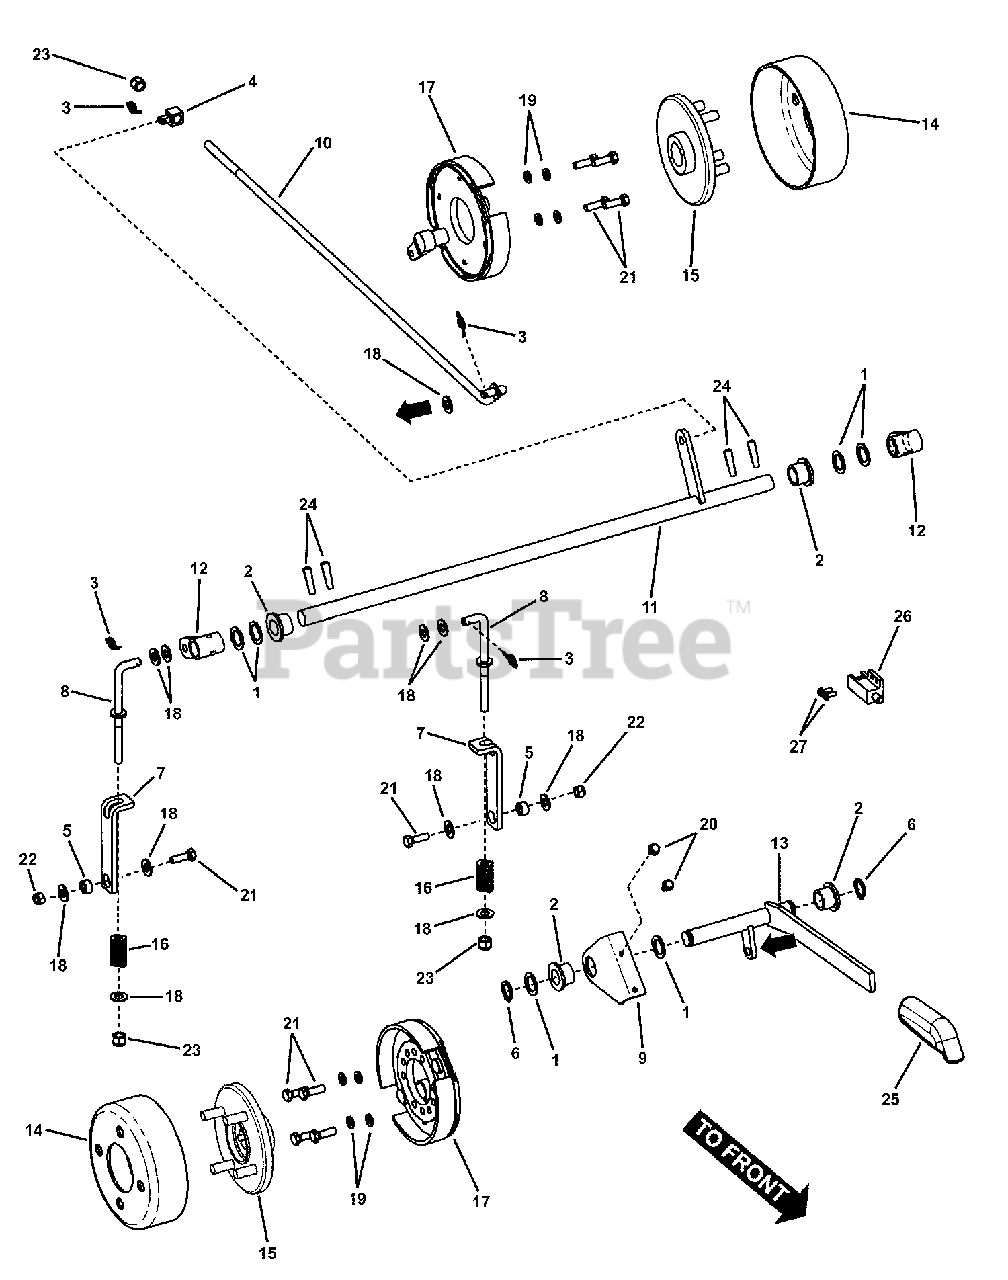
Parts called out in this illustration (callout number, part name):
1	WASHER, .77 I.D. Flat
2	BEARING, 3/4" I.D. Flange
3	PIN, 3/8" Self Locking Cotter
4	SWIVEL, Brake Link-PM
5	SPACER, .340 I.D. x .63 O.D. x .310 Thick
6	RETAINING RING, 3/4" External
7	BRACKET, Brake
8	ROD, Brake Adjustment (3/8-16 thread)
9	BRACKET, Brake Support
10	LINKAGE, Park Brake (3/8-16 thread)
11	WELDMENT, Brake Rod
12	WELDMENT, Brake Hub Rear
13	WELDMENT, Brake Handle
14	BRAKE DRUM
15	ASSEMBLY, Brake Hub
16	SPRING, Brake
17	BRAKE ASSY, (6 inch)
18	WASHER, 3/8" SAE Flat
19	WASHER, 5/16" Split Lock
20	SCREW, 1/4-20 x 1/2" Hex Washer Self-Tap
21	BOLT, 5/16-18 X 1 GD5 YZ
22	NUT, 5/16-18 HEX NYLON LOCK
23	NUT, 3/8-16 HEX NYLON LOCK
24	GROOVE PIN, 1/4 x 1-1/4" long
25	HANDLE GRIP (Simplicity)
26	SWITCH- DPDT (NC/NO)
27	SCREW, #10-24 x 1/2" Hex Washer Self-Tap (Torx)
